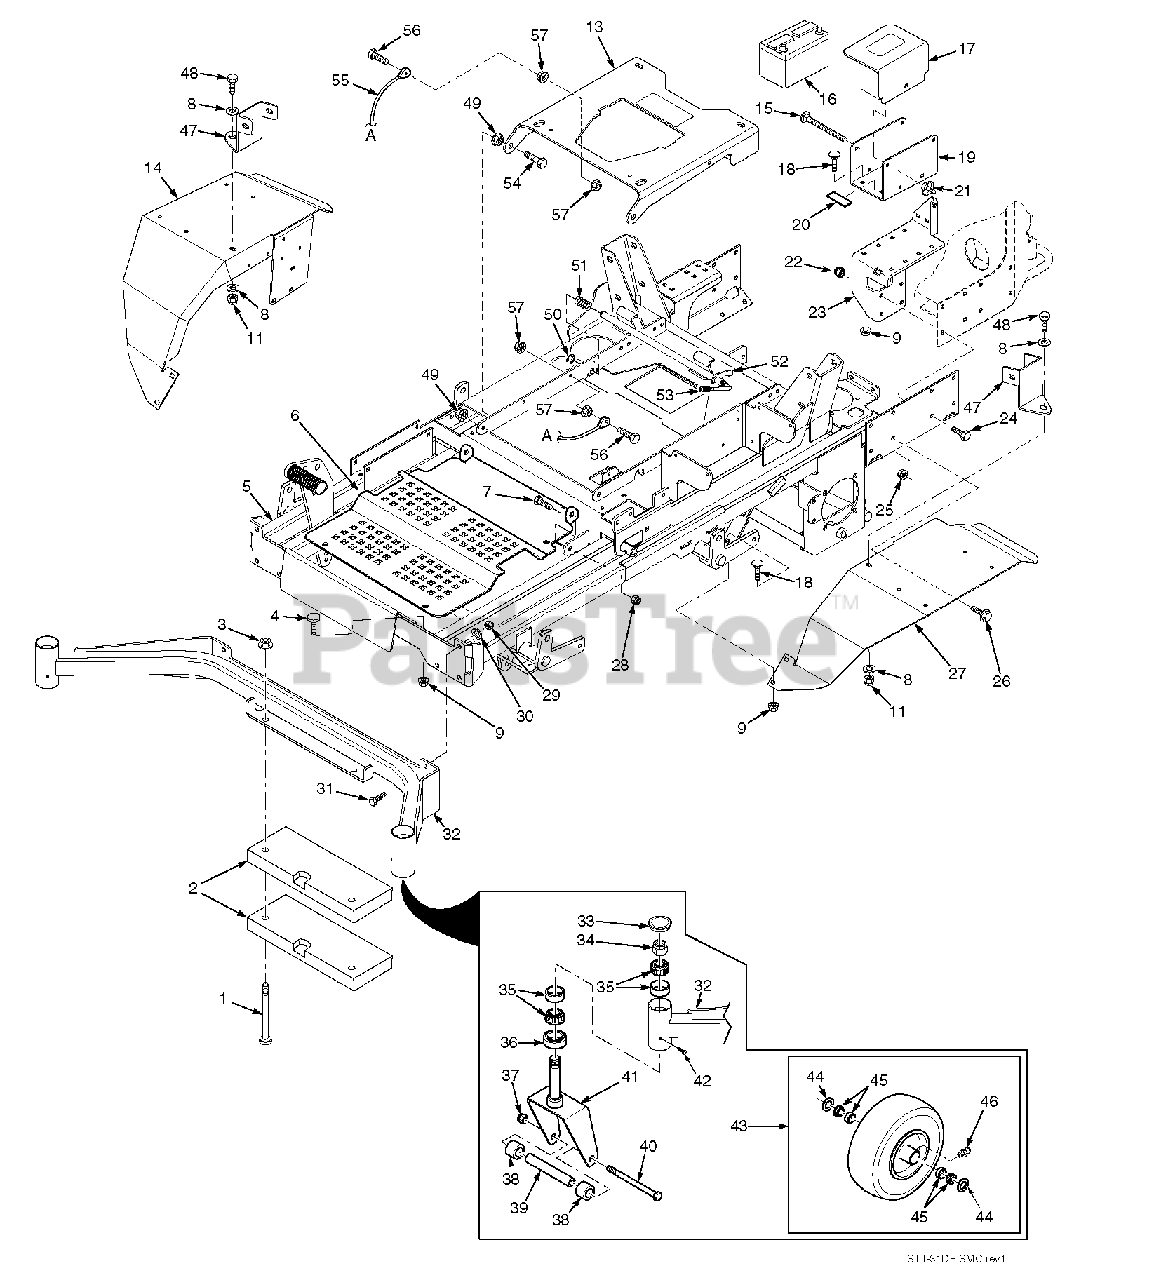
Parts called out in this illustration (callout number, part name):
1	Bolt, Hex Head 1/2-13 x 3.5"
2	Weight
3	Nut, Hex Elastic Stop 1/2-13
4	Bumper, Rubber 5/16-18 x 5/8"
5	Main Frame Assembly w/Decals
6	Foot Plate
7	Bolt, Hex Head 3/8-16 x 1"
8	Flatwasher, 3/8-.391 x .938 x .105
9	Nut, Hex Serrated Flange 5/16-18
10	Bolt, Hex Head 3/8-16 x 2.0"
11	Nut, Elastic Stop 3/8-16
12	Spacer Bushing
13	Seat Plate Weldment w/Decal
14	Fender Weldment, RH
15	Bolt, Carriage 1/4-20 x 6"
16	Battery
17	Cover, Battery
18	Bolt, Carriage 5/16-18 x 3/4"
19	Plate, Battery Box
20	Rubber Pad
21	Wing Nut, 1/4-20 x 3/4"
22	Nut, Elastic Stop 3/8-16
23	Battery Box Mount
24	Bolt, Hex Head 3/8-16 x 1"
25	Nut, Hex Serrated Flange 3/8-16
26	Screw, Hex Serrated Flange 3/8-16 x 1"
27	Fender Weldment, LH
28	Nut, Hex Elastic Stop 3/8-16
29	Nut, Elastic Stop 7/16-14
30	Lockwasher, 7/16"
31	Bolt, Hex Head 7/16-14 x 1-1/4"
32	Extention Weldment, Caster
33	Cap, Grease
34	Nut, Hex Elastic Stop 1.0"-14
35	Bearing W/Race
36	Seal, 2.00" OD. x 1.625" Bore
37	Nut, Hex Elastic Stop 1/2-13
38	Spacer, Caster Wheel
39	Sleeve, Caster Wheel
40	Bolt, Hex Head 1/2-13 x 9-1/2"
41	Yoke Weldment, Caster
42	Plug, 1/4-28 THD Form
43	Wheel Assembly
45	Bearing w/ Race
46	Grease Fitting
47	Bracket, Fender Support
48	Bolt, Hex Head 3/8-16 x 1-1/4"
49	Nut, 7/16-14 Serrated Flange
50	Retaining Ring .625" Ext. "E"
51	Spring, Seat Latch
52	Lever Assembly, Seat Release
53	Grip, Seat Latch
54	Bolt, Hex Head 7/16-14 x 1-3/4"
55	Cable, Seat Stop
56	Bolt, Hex Head, 1/4-20 x 1-1/4"
57	Nut, Hex Serrated Flange 1/4-20
